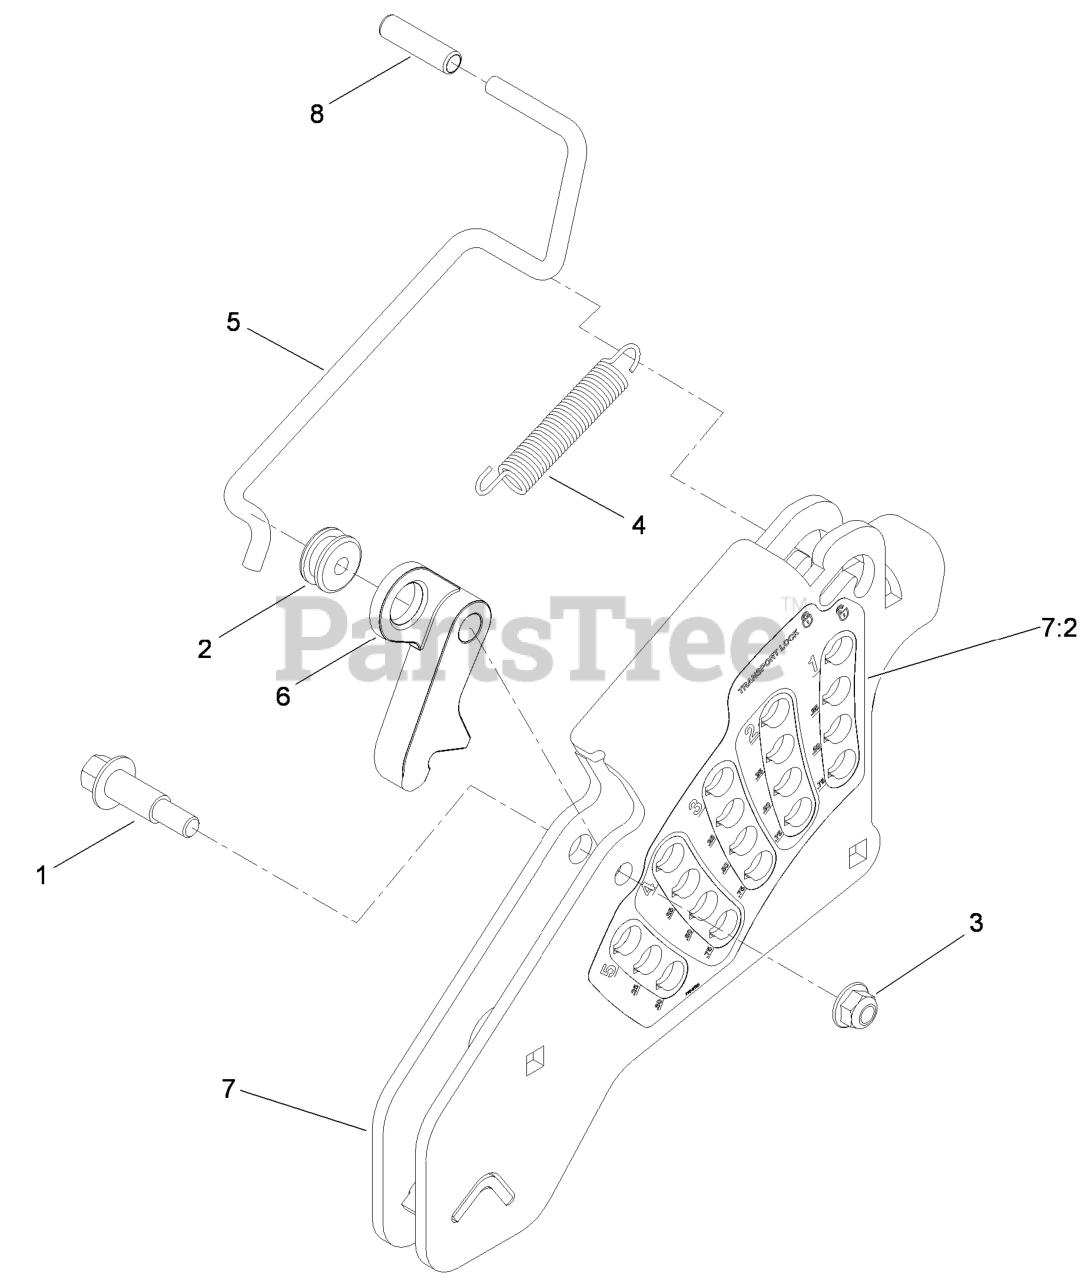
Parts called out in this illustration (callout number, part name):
1	BOLT-SHOULDER
2	GROMMET
3	NUT-HF, NI
4	SPRING-EXTENSION
5	ROD-LOCK, TRANSPORT
6	PAWL-TRANSPORT, HOC
7	HOC PLATE ASM
7:2	DECAL-HOC
8	GRIP-LEVER
